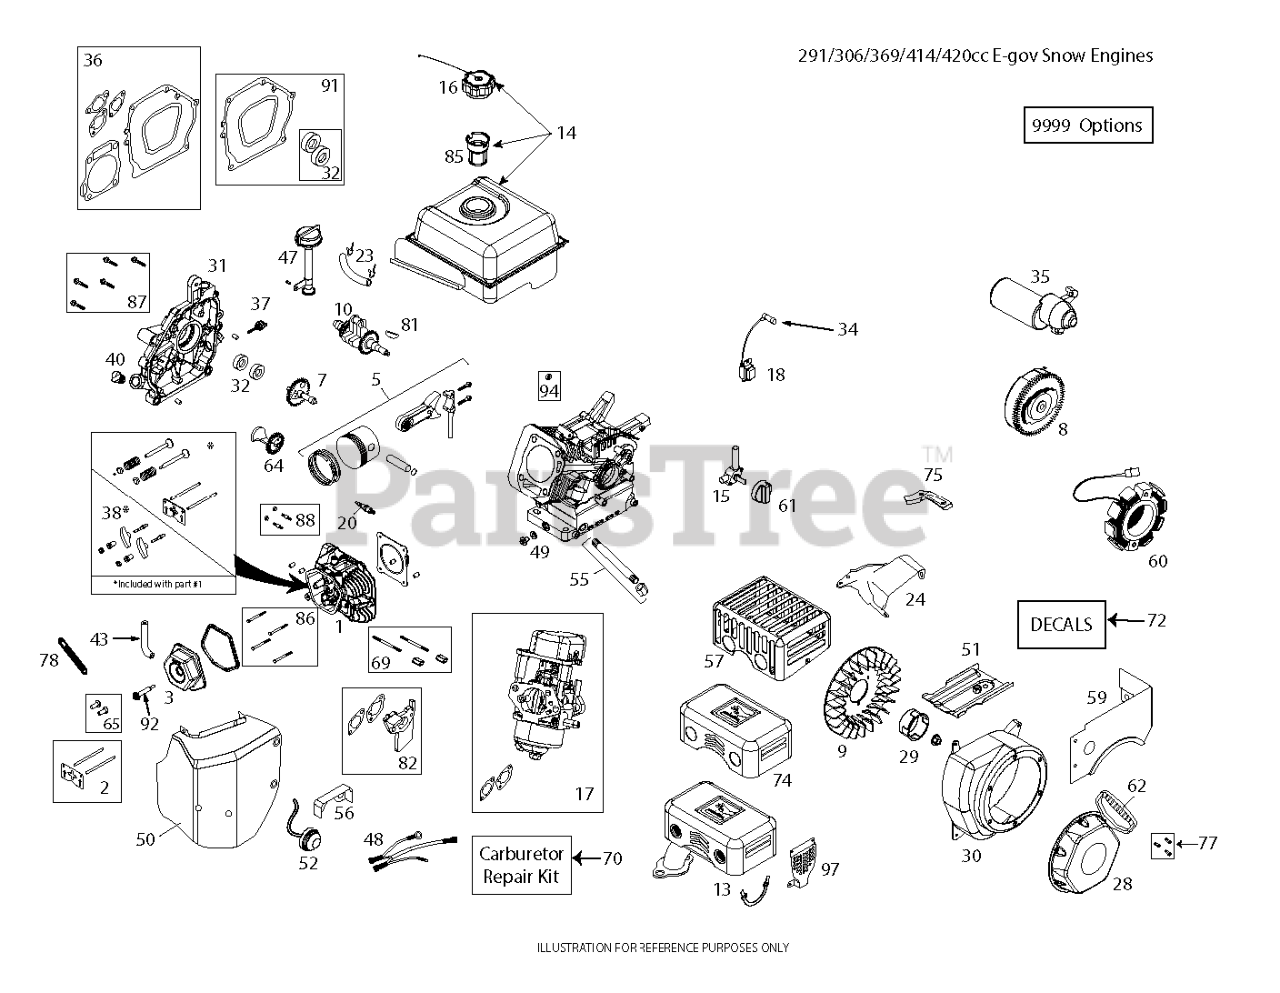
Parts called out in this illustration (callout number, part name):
1	CYLINDER HEAD LCT 178 INCLUDES
2	PUSH ROD TAPPET KIT
3	VALVE.COVER.LCT.414CC.
5	PISTON ROD ASM.LCT SK3691400.1
7	CAMSHAFT(SK4141600)
8	FLYWHEEL.EL.ST.SKSN4408.1
9	FLYWHEEL.FAN(SK4144000)
10	CRANKSHAFT KEYED #18 LCT 414C
13	MUFFLER ASSY LCT SNO
14	FUEL.TANK.ASSY.SNOW(SKSN4300)
15	FUEL.PETCOCK.SNOW(SKSN4900)
16	FUEL.TANK.CAP.SNOW(SKSN4301)
17	Carburetors
18	IGNITION.COIL.(CDI).291-414CC
20	PLUG.SPARK
20	SPARK.PLUG(2083810)
23	FUEL HOSE KIT
29	STARTER CUP
30	BLOWER LCT 414CC
32	OIL SEAL KIT NON-GENERATOR
34	SPARK.PLUG.BOOT.SNW,SKSN4691.1
36	GASKET KIT ENGINE LCT 369
37	DIPSTK.OIL.BLK.LCTSK4143711.1
38	ROCKER ARM KIT
40	NONREMVABLE.OIL.PLUG(SK4143715
43	BREATHER TUBE LCT 291/369/414
47	HIGHOIL.FILL.ASSY.KIT(SKSN4911
49	KIT.OIL.DRAIN.PLUG(SK2089911
50	Carburetors
51	SHIELD.CYLINDER.SNOW(SK4141010
52	PRIMER.BULB.ASSY(SKSN4304)
55	OIL PIPE DRAIN EXTENDED.LCT SK
56	SHIELD.VAPOR(SKSN4606)
57	CE COMPLIANT MUFFLER SHEILD
59	FUEL TANK SKIRT.LCT.369/420CC
60	Charging Station
61	FUEL KNOB-SNOW
62	HANDLE.RECOIL.DELUXE.LCT
64	COUNTER WEIGHT KIT
65	TAPPET KIT.LCT.SK2911005.1
69	STUD.CARB.MOUTING.KIT.414CC
70	CARBURETTOR REPAIR KIT 291CC/4
72	ARIENS 414 SNOW DECAL KIT
74	MUFFLER SHIELD
75	SHIELD.U/FYWHL.CHARG(SKSN4604)
77	BOLT.KIT.RECOIL.LCT.ALL.ENGINE
78	STRAP.RETAINING.TUBE.BREATHER.
81	KEYS.FLYWHEEL.208/414CC.5PACK
82	SPACER.CARBURETOR.414CC.LCT
85	STRAINER.FUEL.TANK.LCT.208CC
86	KIT.BOLT.CYLINDER.HEAD.(4PC)
87	KIT.BOLT.CRANKCASE.COVER.414CC
88	STUD.MUFFLER.KIT.LCT
91	GASKET KIT CRANKSHAFT.LCT
92	CENTER VALVE COVER BOLT
94	SEAL GOVERNOR SHAFT OIL.LCT
97	GUARD.EXHAUST
9999	HIGH ALTITUDE JET 6000FT
9999	KIT.BOLT.LCT.SK9990.1
